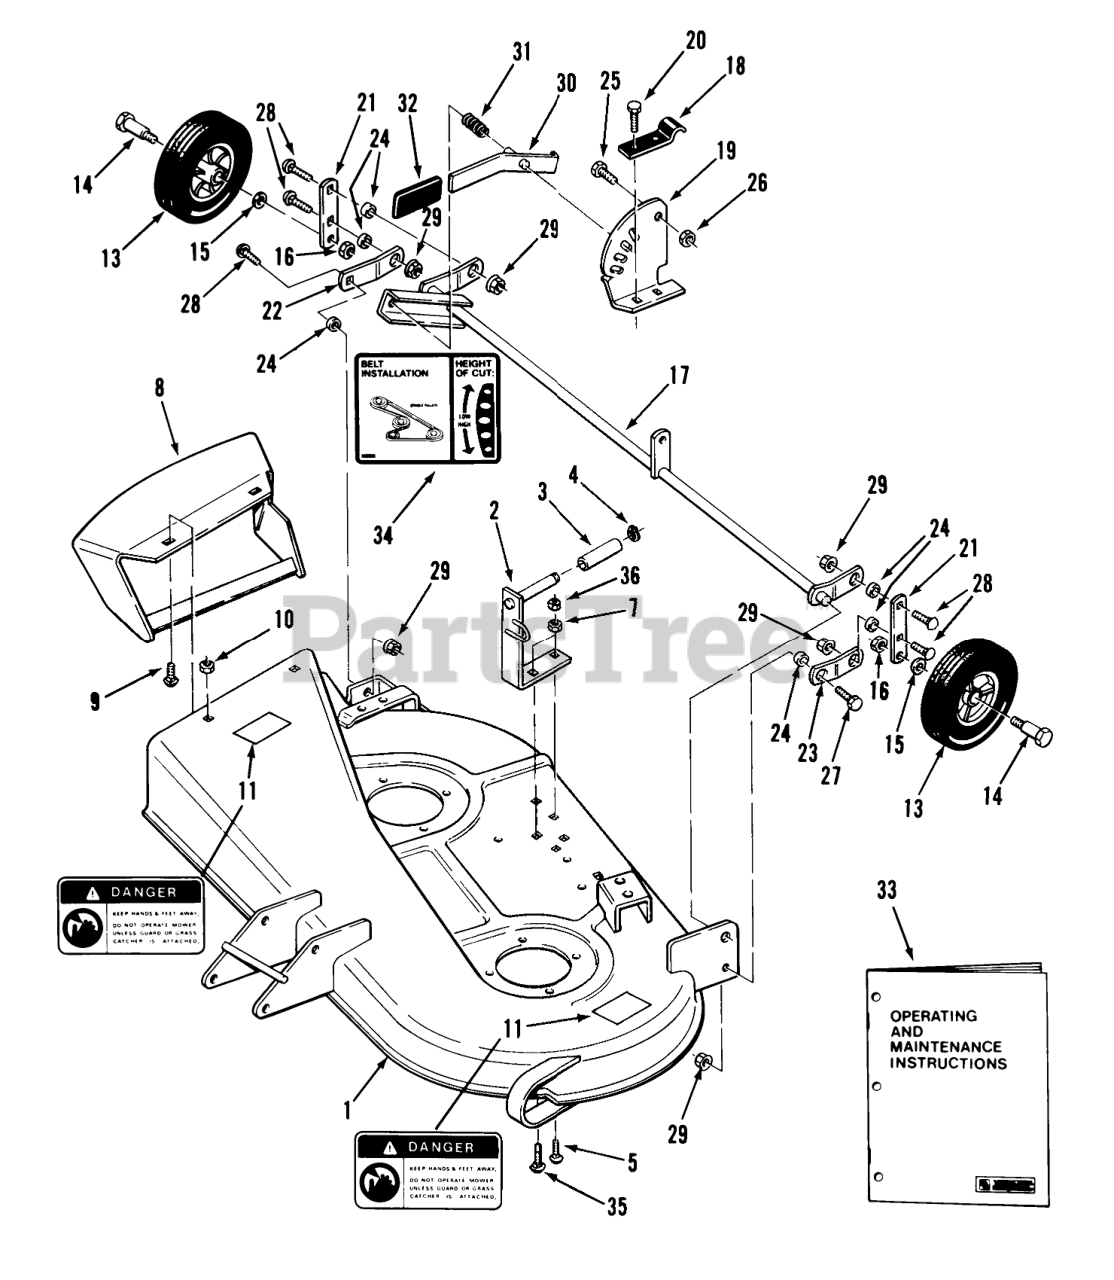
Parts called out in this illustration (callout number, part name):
1	ASSY 32" MOWER SI R
2	ASSY-BRACKET GUID R
3	SPACER
4	Snap Ring
5	CARRIAGE BOLT -9
7	Nut
8	ASSY-CHUTE EXT R
9	Bolt
10	Nut
11	Danger Decal
13	WHEEL-GAUGE
15	WASHER
16	Nut
17	Gage Wheel Support
18	Bracket-Pivot
19	Quadrant
20	Bolt
21	LINK R
22	ARM-PIVOT RH R
23	Arm LH
24	SPACER
26	Nut
27	BOLT
28	Bolt
29	LOCKNUT-FLANGE
30	Lever
31	SPRING-COMPRESSION
33	Operating & Maintenance Instructions
34	DECAL-BELT&HEIGHT
35	Bolt-Carriage
